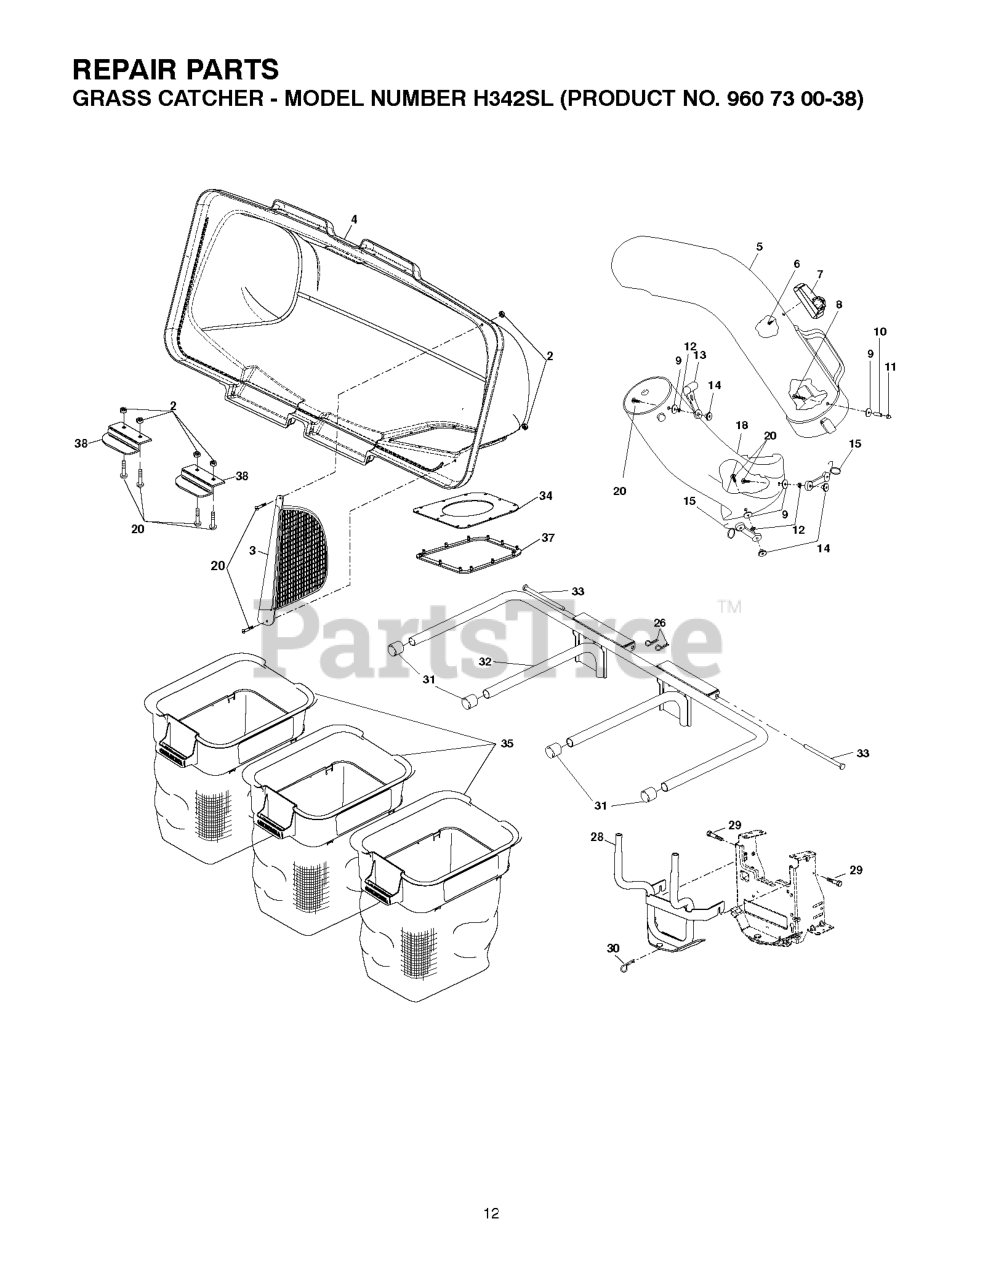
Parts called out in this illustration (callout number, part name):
3	SCREEN.COVER.BAGGER
4	COVER.ASM.3BIN.GENERIC.
5	CHUTE.UPPER.42"
7	INDICATOR ASM BAG
8	SCREW
9	RP STEEL WASHER
11	NUT
12	LOCKWASHER (3 2)
13	LATCH.HOOD.
14	WELDNUT
15	LATCH ASSY
18	LOWER CHUTE FOR 42" BAGGER
20	SCREW
26	Retainer Spring
28	BRACKET.BAGGER.3-BIN.BLACK
29	SHOULDER BOLT, SELF-TAP
30	SPRING.RETAINER.YELLOW.ZINC
31	PLUG, TUBING END
32	BAGGER.ASM.FRAME.3BIN.BLACK
33	BAGGER.HINGE.PIN
34	SEAL.BAGGER.TOP.3-BIN.BLK
35	CONTAINER BAG, SOFT
37	GASKET.COVER.BAGGER
38	LATCH CER38
